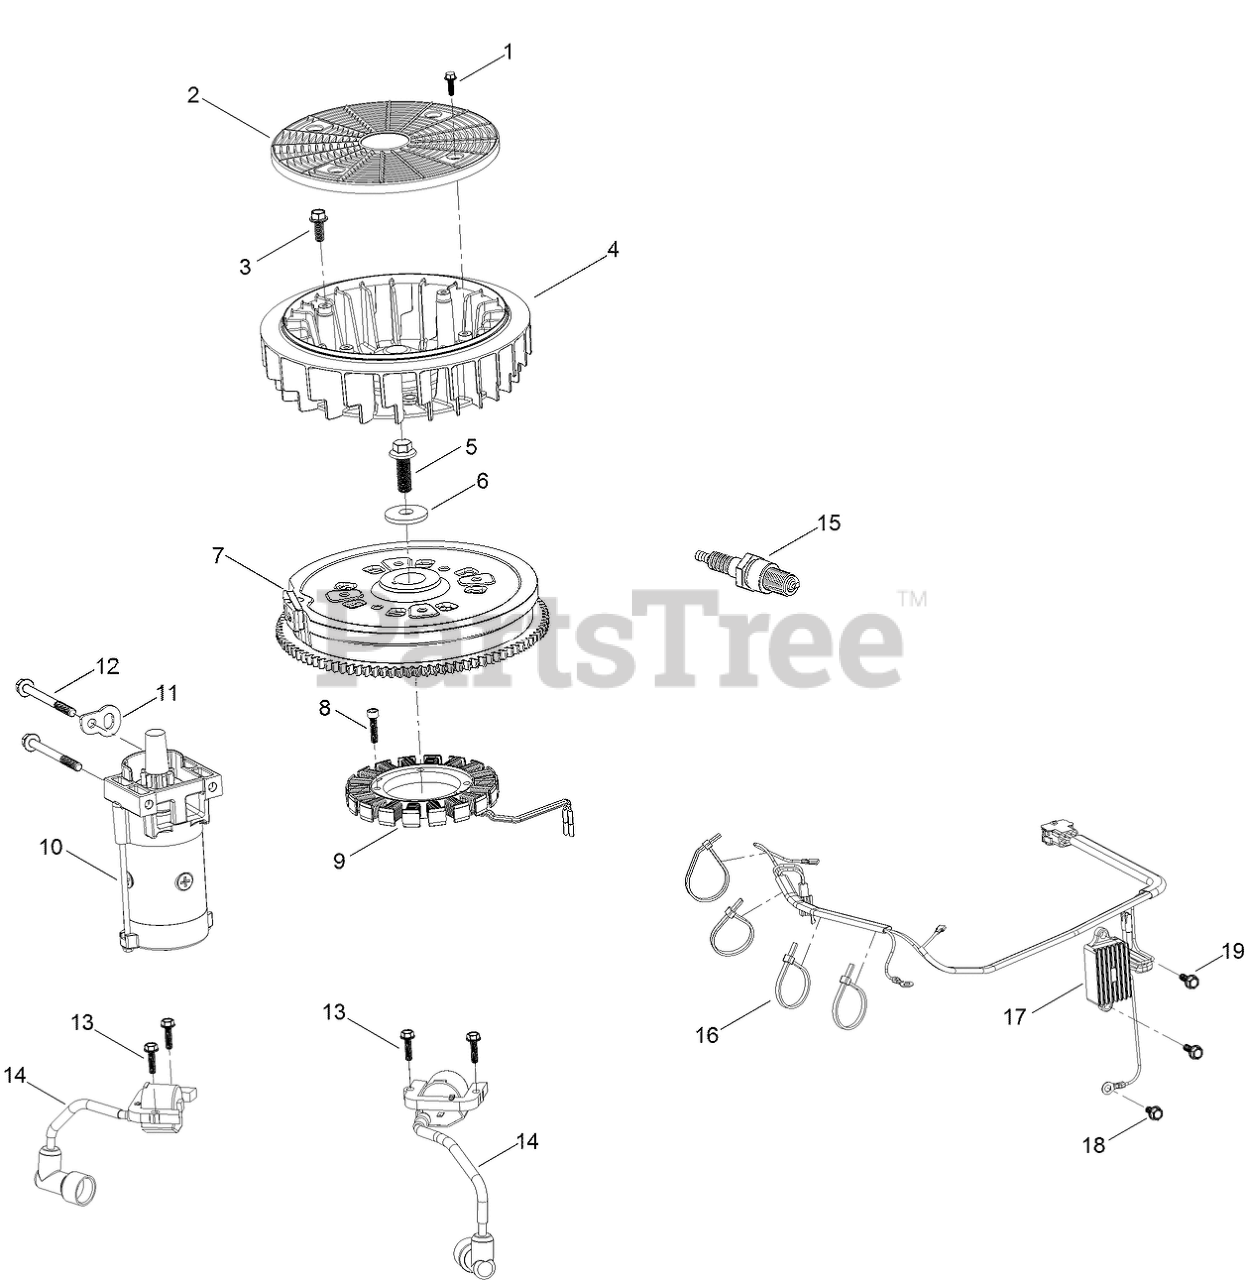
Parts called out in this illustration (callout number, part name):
1	SCREW-HWH
2	SCREEN-ROTATING
3	SCREW-HWH
4	FAN-COOLING
5	SCREW-HWH
6	WASHER-FLAT
7	FLYWHEEL
8	SCREW-HSH
9	ALTERNATOR
10	MOTOR-STARTER
11	BRACKET-LIFT
12	SCREW-HHF
13	BOLT-FLANGE
14	IGNITION COIL ASM
15	SPARK PLUG
16	TIE-ZIP
17	REGULATOR-VOLTAGE W/HARNESS
18	SCREW-HHF
19	SCREW-HHF
